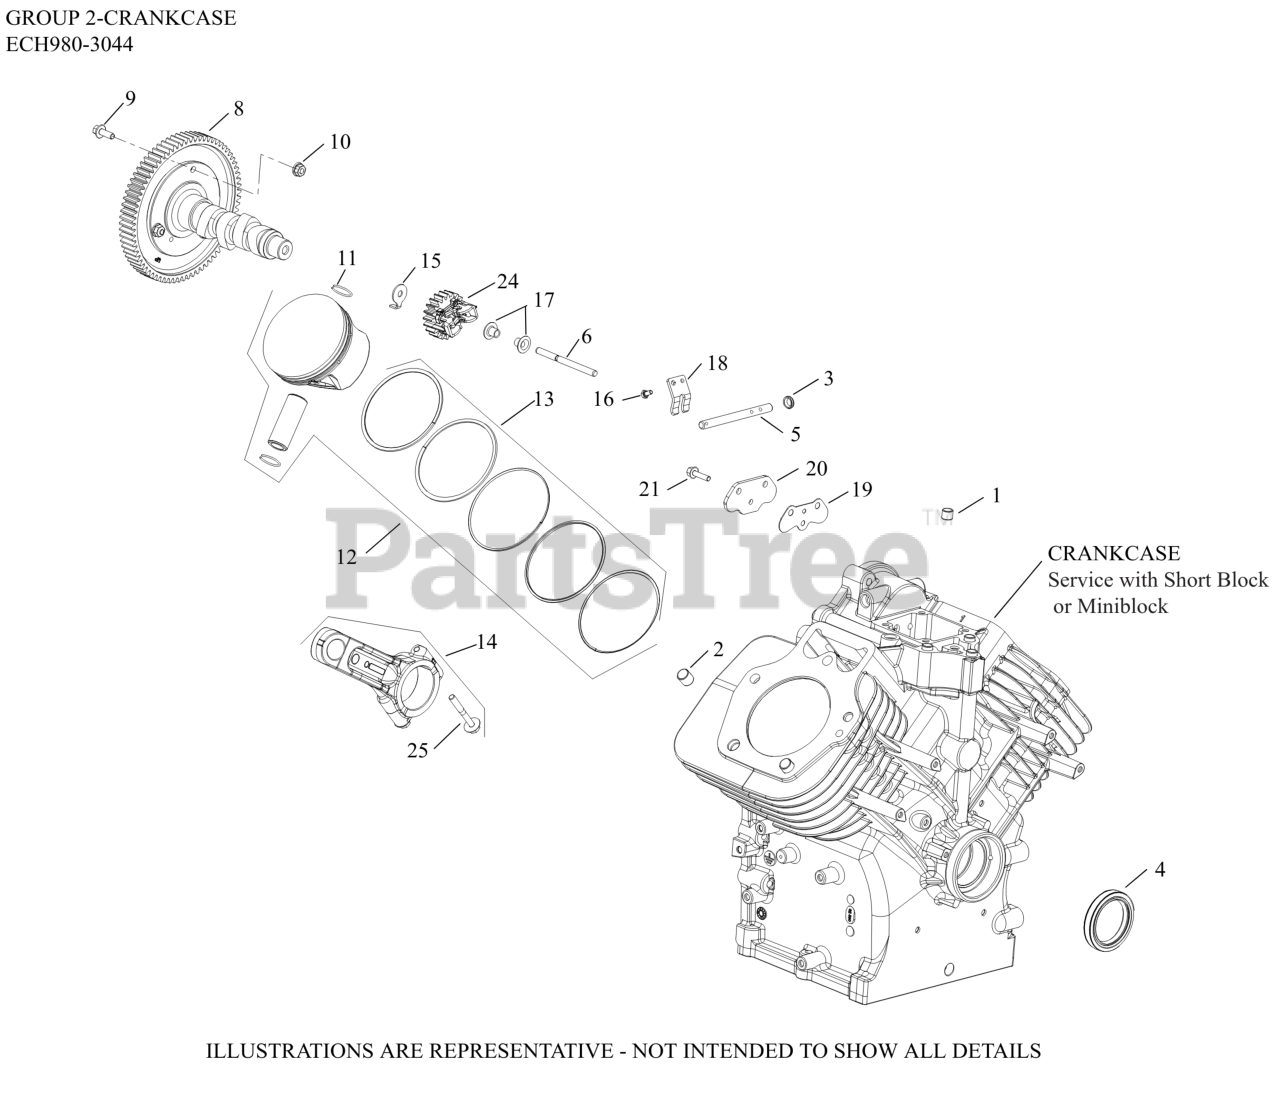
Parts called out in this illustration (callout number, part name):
2	PIN, LOCATING
3	SEAL, GOVERNOR CROSS SHAFT
4	SEAL, OIL
5	SHAFT, GOVERNOR CROSS
6	SHAFT, GOVERNOR GEAR
8	KIT, CAMSHAFT-USE 62 010 12-S
9	SCREW,HEX FLNGE
10	NUT, FLG M6X1.0
11	RETAINER, PISTON PIN
12	RING, SET PISTON (STD)
13	KIT, PISTON (STD)
13	KIT, PISTON (0.25 OS)
13	KIT, PISTON (0.50 OS)
14	CONNECTING ROD ASSEMBLY
15	TAB, LOCKING
16	SCREW, HEX HEAD
17	PIN, GOVERNOR REGULATING
18	YOKE, GOVERNOR
19	GASKET, LIFTER FEED COVER
20	KIT, COVER, LIFTER FEED
21	SCREW, HVY FLG M5X0.8X20
24	KIT, GOVERNOR GEAR
25	KIT, ROD BOLTS
